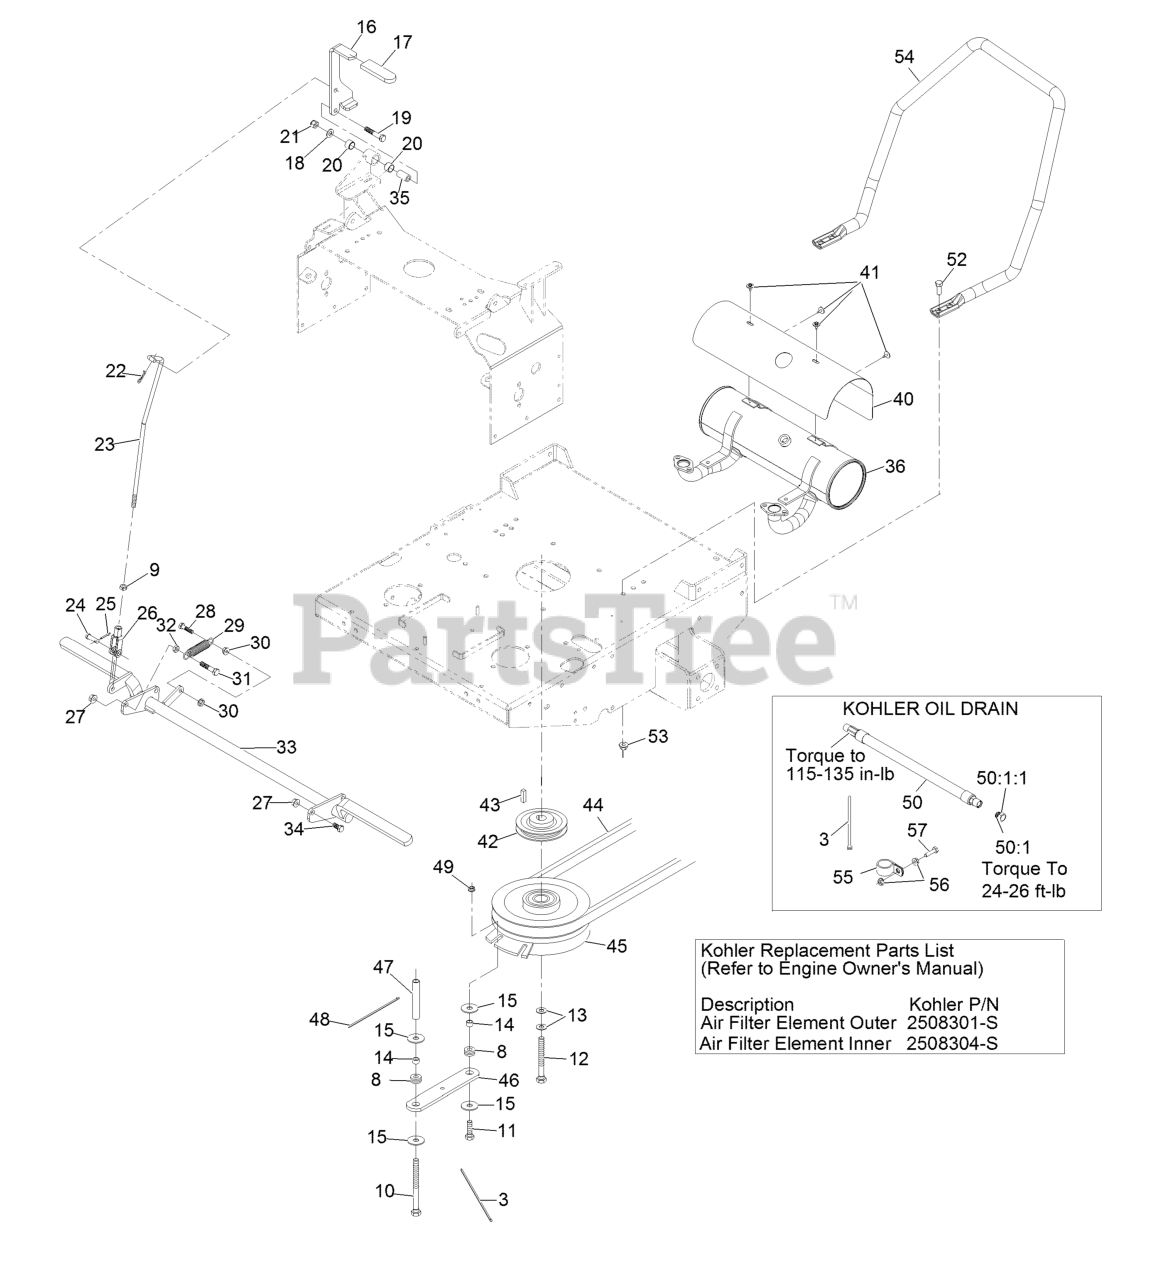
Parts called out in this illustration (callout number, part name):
3	TIE-PLASTIC
8	GROMMET
9	NUT-HJ
10	SCREW-HH
11	SCREW-HH
12	SCREW-HH
13	WASHER-SPRING
16	LEVER, PARK BRAKE W/DECAL
17	GRIP-LEVER
18	WASHER-FLAT
19	SCREW-HH
20	SLEEVE-BUSHING
21	NUT-LOCK, NI
22	PIN-COTTER
23	LINKAGE, PARK BRAKE
24	PIN-CLEVIS
25	PIN-COTTER
26	YOKE-LINKAGE, BRAKE
27	NUT-HHF, WHIZ
28	SCREW-HH, SPECIAL
29	SPRING-IDLER
31	SCREW-HH
32	NUT-JAM
34	SCREW-HH
35	BUSHING-PIVOT
36	MUFFLER-TTX, EFI
40	SHIELD-MUFFLER,TTX EFI
41	SCREW-HH, THREAD FORMING
42	PULLEY
44	BELT,DECK DRIVE
45	CLUTCH ASM
46	STRAP-CLUTCH, BRAKE
47	SPACER,SHIELD
48	TIE-CABLE
50	OIL DRAIN HOSE ASM
50:1	PLUG-HH
50:1:1	O-RING
52	SCREW-HH
53	NUT-HF, NI
54	GUARD,AIR CLEANER
55	CLIP-LOOM
57	SCREW-HH
